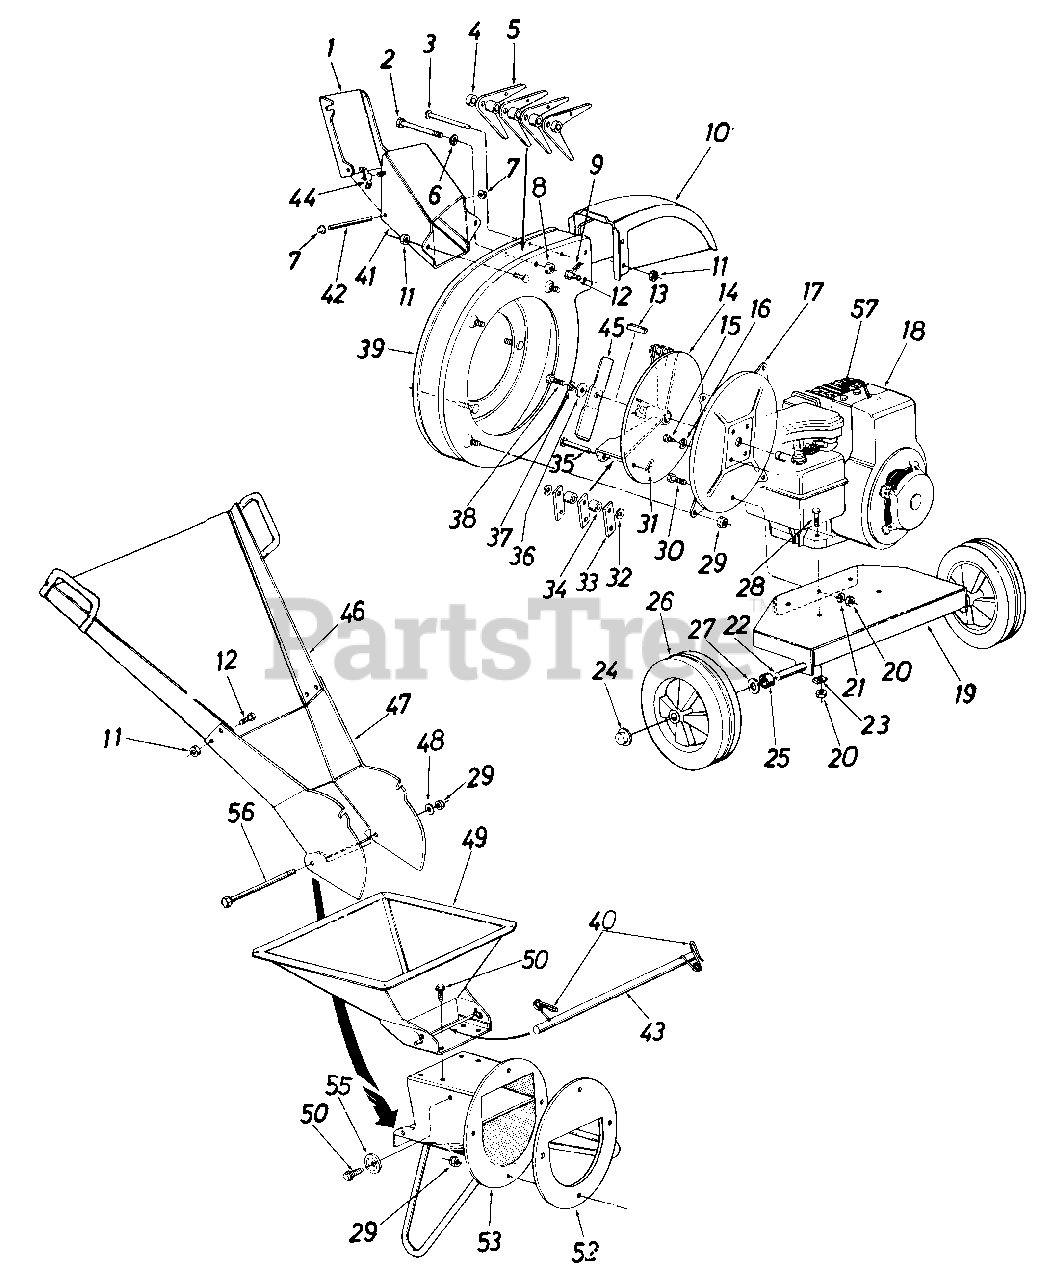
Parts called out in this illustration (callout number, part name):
1	Door Chip It
2	Hex Bolt 1/2-20 x 4.50" Lg.*
3	Clevis Pin
4	Flail Spacer 7/32" Lg.
5	Cutting Finger
6	L-Wash. 1/2" I.D.*
7	Palnut 3/16" Dia.
8	Hex Jam Nut 1,2-20 Thd.*
9	Cotter Pin 3132" Dia. x 3/4" Lg .
10	Chute Deflector
11	L.-Nut 1/4-20 Thd.
12	Hex Bolt 1/4-20 x .50" Lg.*
13	Sq. Key 1/4" x 2.00" Lg.
14	Impeller Assembly
15	Hex Bolt 5/16-24 x 3/4" Lg.
16	L.-Wash. 5/16" I.D.*
17	Hopper to Engine Mtg. Plate
18	Engine
19	Engine Mounting Plate
20	Hex Nut 5/16-24 Thd.*
21	L.-Wash. 5/16" I.D.*
23	Special L.-Wash. 5/16" I.D.
26	Wheel Ass'y.-Comp.
27	Fl.-Wash. .50" I.D.
28	Hex Bolt 5/16-24 x 1.50" Lg.*
29	Elastic Lock Nut 5/16-18 Thd.
30	Hex Bolt 5/16-24 x .62" Lg.*
31	Cotter Pin 1/8" Dia. x 1.00" Lg.* (Special)
32	Fl.-Wash. .531" I.D. x 937 O.D. x .09
33	Flail
34	Flail Spacer 23/32" Lg.
35	Clevis Pin .50" Dia. x 3.0" Lg.
36	Fl.-Wash. .406" I.D. x 1.25" O.D. Hdn.
37	L.-Wash. 3/8" I.D. H.D.
38	Hex Bolt 3/8-24 x 2.0" Lg. H.T.
41	Chip-lt Guide Ass'y.
42	Hinge Pin
43	Release Bar
44	Wing Nut Elastic 1/4-20 Thd.
47	Lower Leaf Ramp Section
48	Fl.-Wash. 5/16" I.D.
49	Hopper Assembly
50	Hex Wash. Hd. Self-Tap Scr. 5/16-18 x .75" Lg.
52	Back-Up Plate
53	Inlet Guide Assembly
55	Stop Washer
56	Hex Bolt 5/16-18 x 8.38" Lg.
57	Spark Plug Elbow (Optional)
